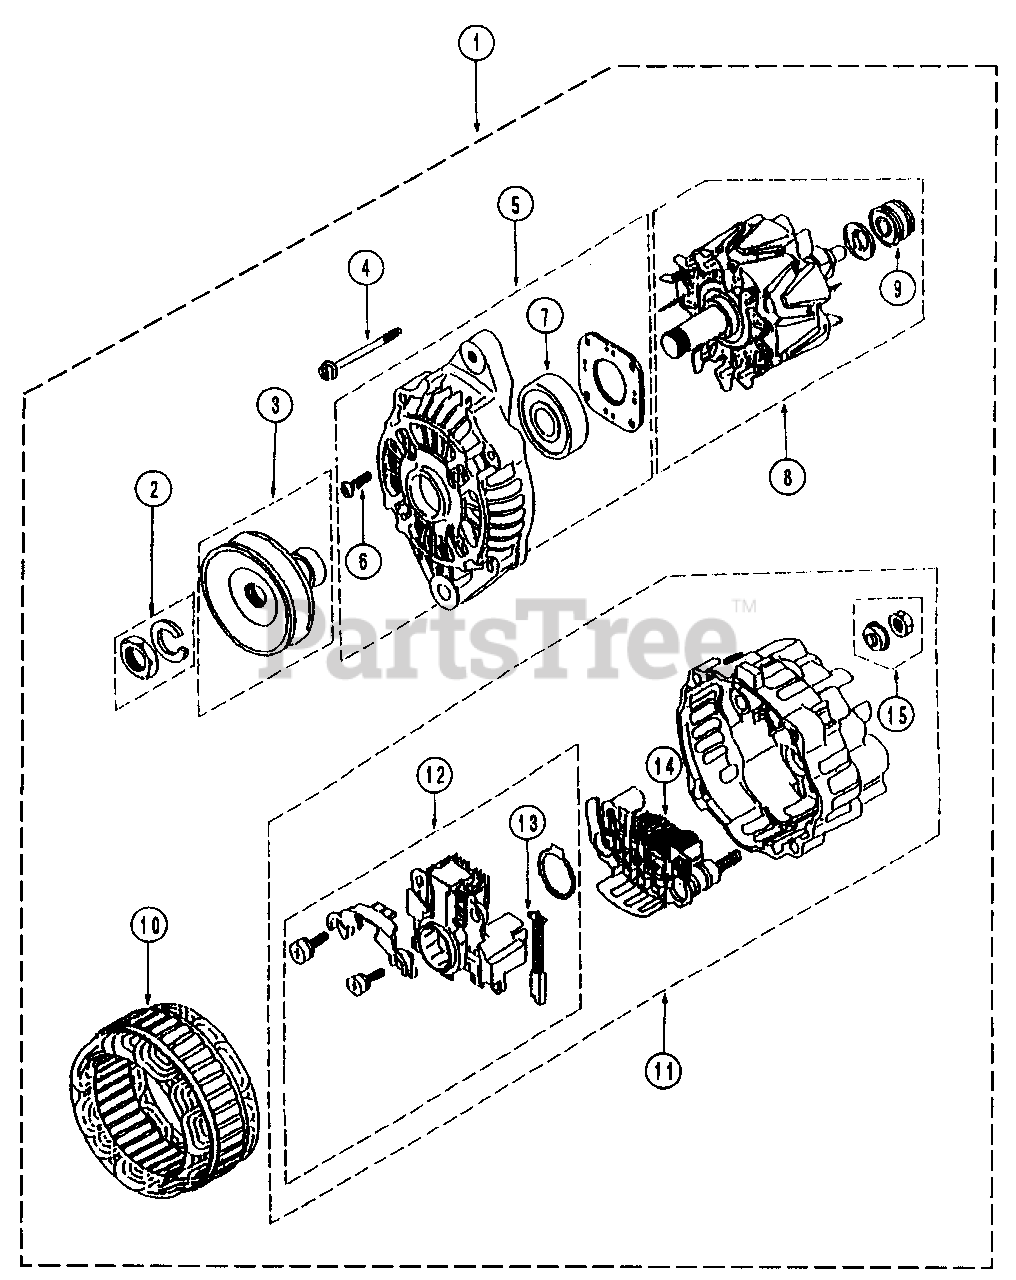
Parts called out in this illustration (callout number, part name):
1	Alternator Ass'y
2	Nut Set
3	Pulley Ass'y
5	Bracket Ass'y, Front
7	Bearing, Front
9	Bearing, Rear
10	Starter Ass'y
11	Bracket Ass'y, Rear
12	Regulator Set
14	Rectifier Ass'y
15	Nut Set
